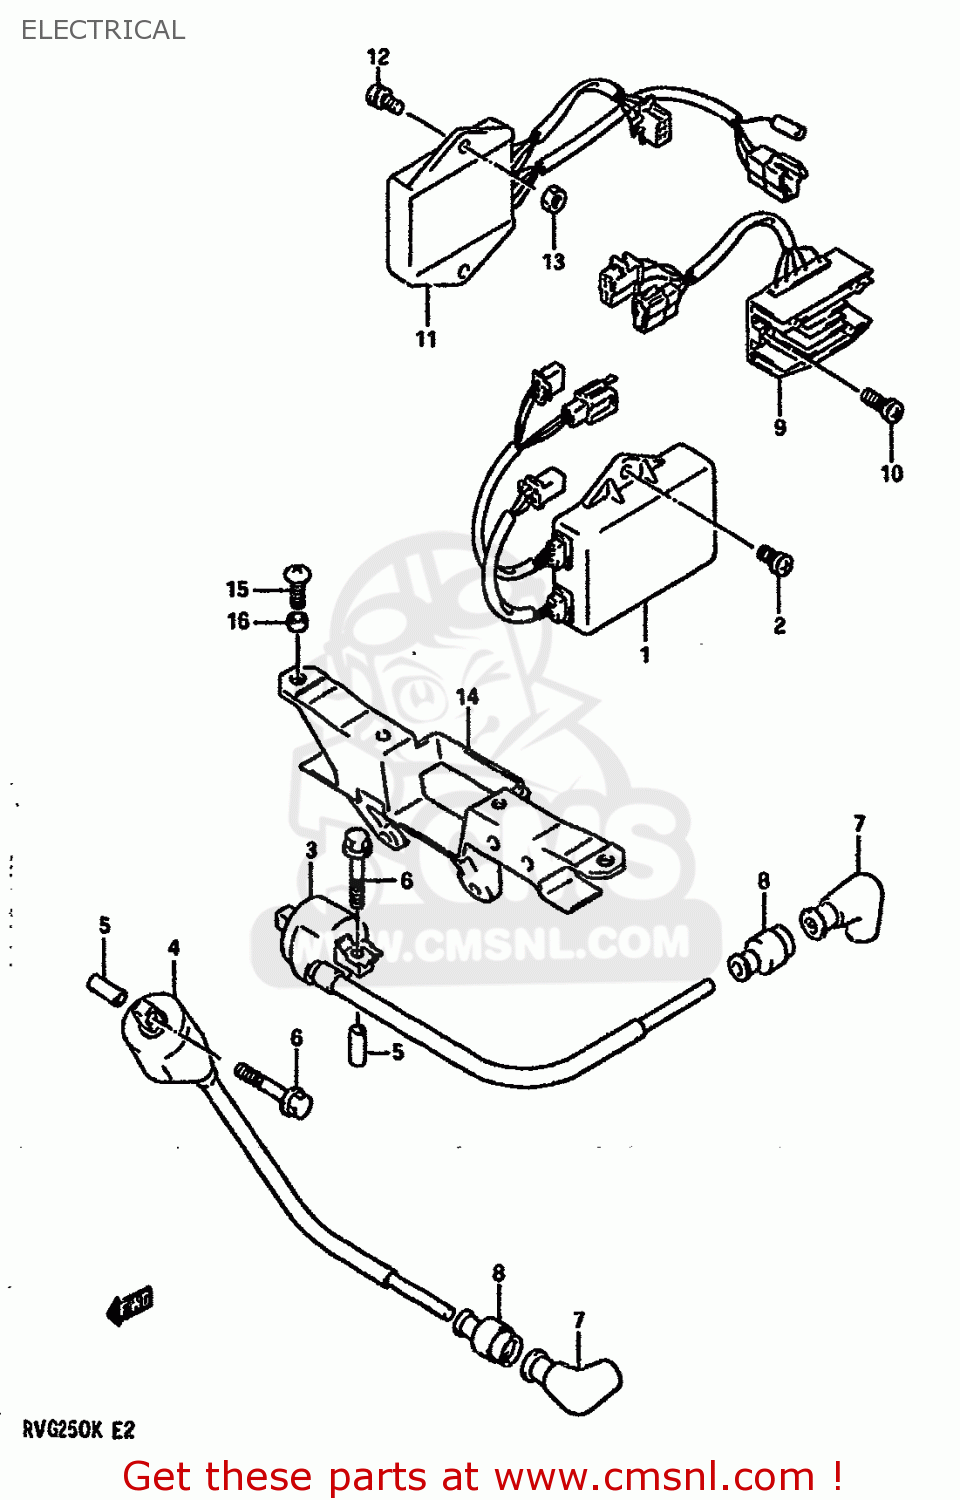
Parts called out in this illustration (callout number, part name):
1	CDI UNIT
2	SCREW
3	COIL ASSY,IGNITION NO.1
4	COIL ASSY,IGNITION NO.2
5	SPACER
6	SCREW
7	CAP,SPARK PLUG
8	SEAL,HIGH TENSION CORD
9	RECTIFIER
10	SCREW
11	CONTROL UNIT,EXHAUST VALVE
12	SCREW
13	NUT
14	HOLDER,ELECTRIC PARTS
15	SCREW
16	SPACER (6.1X9X3.8)
